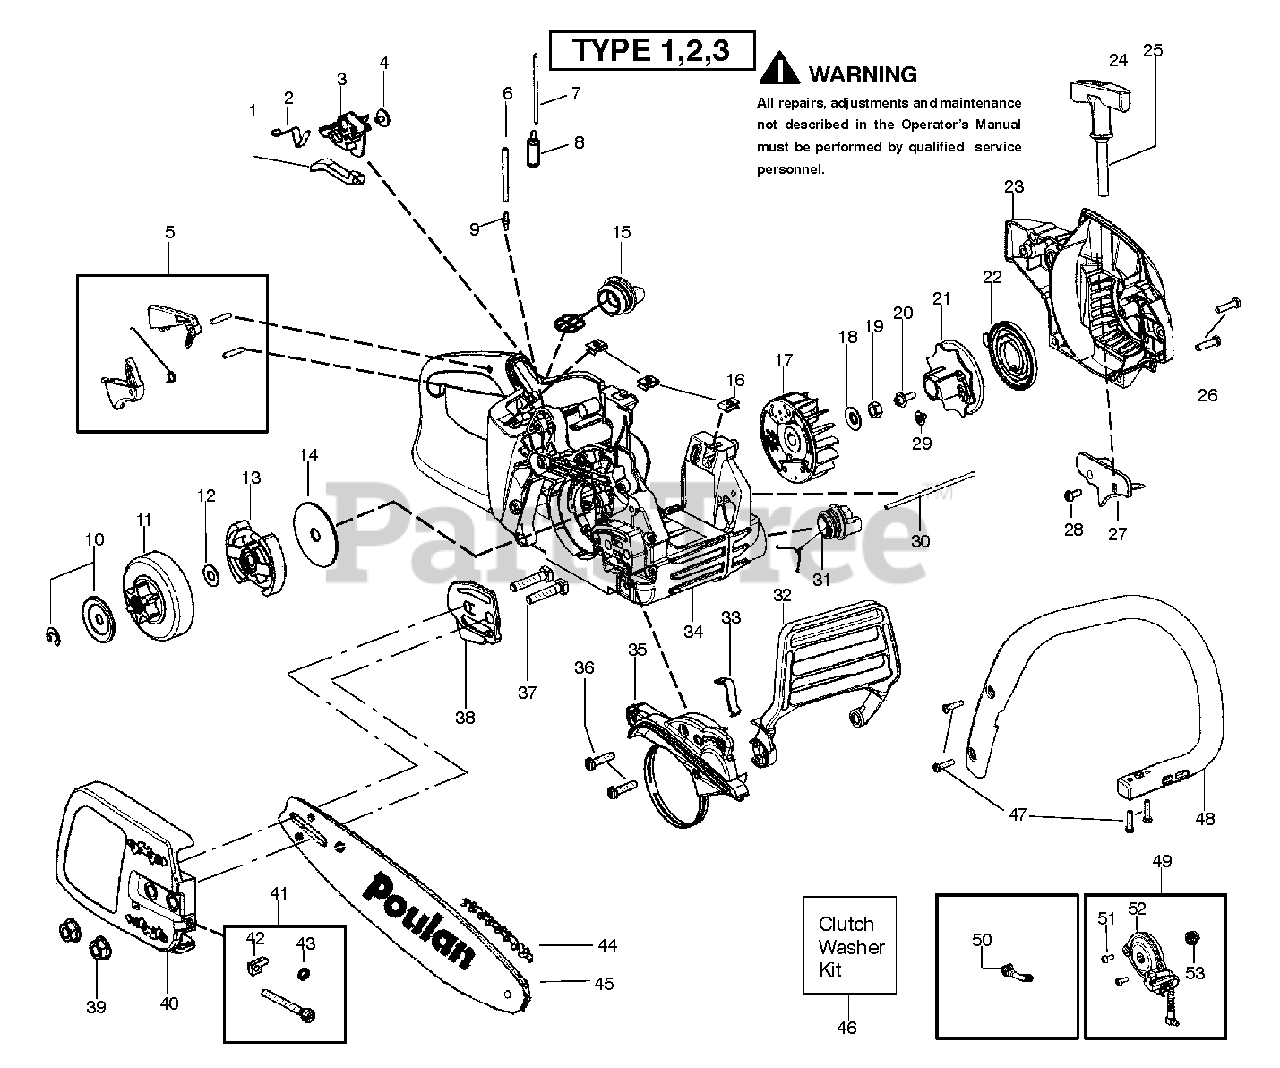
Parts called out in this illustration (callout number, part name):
1	KNOB CHOKE
2	SPRING IGNITION SWITCH
3	LEVER IGNITION SWITCH
5	KIT TRIG AND LOCKOUT
6	LINE KIT
6	KIT FUEL LINE
7	KIT-LINE
7	KIT FUEL LINE
8	ASSY FUEL PICK UP W/LINE
9	FUEL LINE FITTING
11	ASSY CLUTCH DRUM 3/8
13	ASSY CLUTCH
14	WASHER LARGE CLUTCH-SAS
15	FUEL CAP ASSY W/RET
17	ASSEMBLY FLYWHEEL
18	WASHER-FLYWHEEL
19	NUT-FLYWHEEL
21	STARTER PULLEY
23	FAN HOUSING
24	HANDLE STARTER
25	KIT-ROPE
26	SCREW M5.38-14X22.225MM
27	BAFFLE FAN HOUSING
28	SCREW 6-19X.437
30	ASSEMBLY-OIL-VENT
31	OIL TANK CAP
32	HANDGUARD
33	SPRING HANDGUARD
34	ASSEMBLY CHASSIS SAS NAV BLACK
34	CHASSIS
35	KIT CHAIN BRAKE
36	SCREW M5.38-14X22.225MM
38	PLATE BAR MOUNTING
40	HOUSING CLUTCH COVER(PLN GRN)
40	ASSY CLUTCH COVER PLN GREEN
41	RETAINER
42	ADJUST PIN,BAR 36/41
43	RETAINER
44	ACCY-PLN CHN 16" 91VJ 56DL 3/8
45	BAR 16"SN .050 3/8 INTZ
45	BAR 16" .050 3/8 .041 56DL
46	KIT SAS CLUTCH WASHER
47	SCREW M5.38-14X22.225MM
48	HANDLE FRONT
49	KIT OIL PUMP
50	ASSY PICK UP OIL TANK
51	SCREW 6-19X.437
52	ASSY OIL PUMP
53	WORM GEAR
